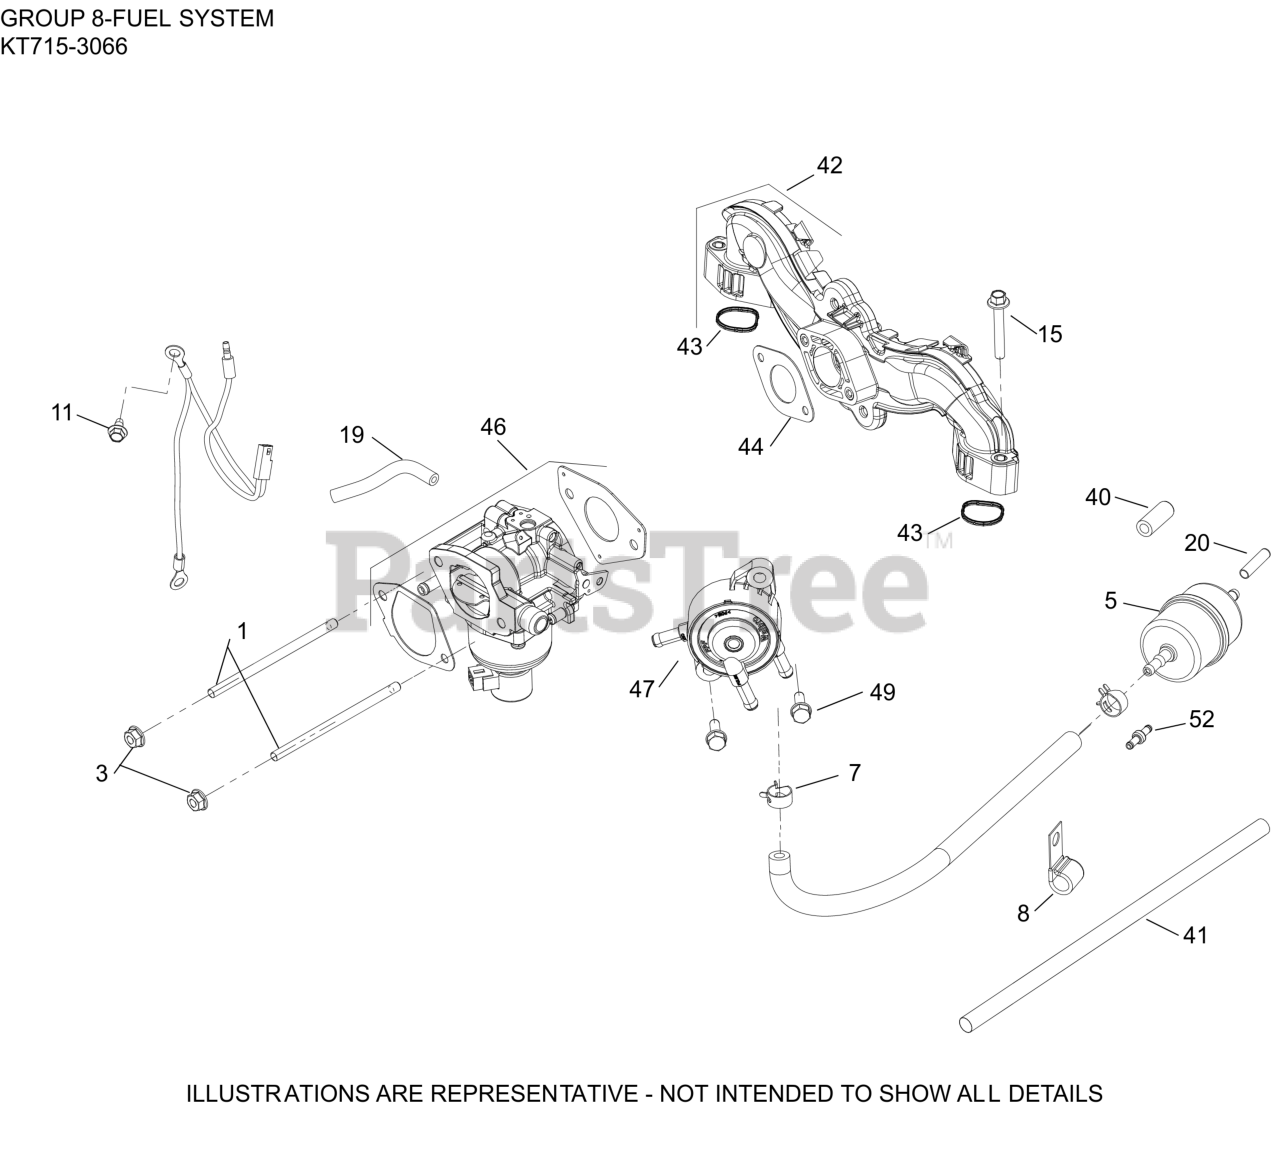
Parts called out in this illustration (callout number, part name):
3	NUT, FLG M6X1.0
5	FILTER, FUEL
7	SPRING CLAMP, HOSE
8	CLIP, CABLE (KM)
11	SCREW, THREAD FORMING
15	SCREW, FLG M6X1.0X40
19	HOSE, EVAPORATIVE 20"- (#24326143S)
20	CAP, MASKING
40	MASKING CAP
41	SLEEVE, ANTI-ABRASION
42	INTAKE MANIFOLD W/GASKETS
43	O-RING, INTAKE PORT
44	GASKET, CARBURETOR (PIM, CV)
46	KIT,CARB (NIKKI)
47	PUMP, FUEL (PULSE)
49	SCREW, HEX HEAD
52	FITTING, FUEL SYSTEM
NI	KIT, HIGH ALT (4000-8000 FT)(NIKKI)
NI	KIT, OVERHAUL NIKKI G-TYPE TWIN
NI	KIT, BOWL WITH O-RINGS NIKKI G-TYPE TWIN
NI	KIT, FLOAT AND NEEDLE NIKKI G-TYPE TWIN
NI	KIT,CHOKEREPAIR NIKKI G-TYPE T-DISC.
NI	KIT,THROTTLE SHAFT(19MM)NIKKI-DISC.
